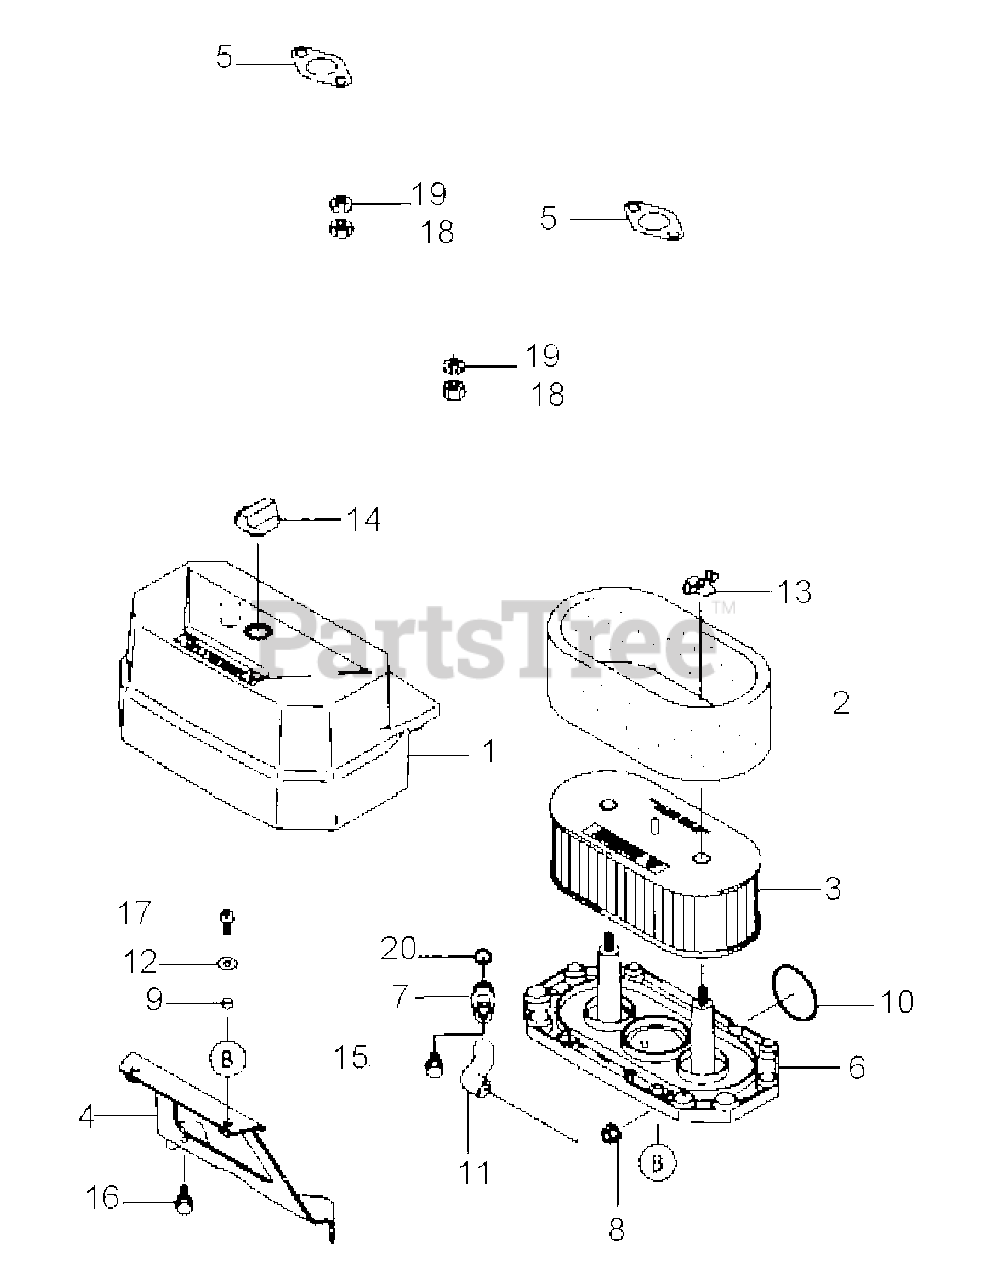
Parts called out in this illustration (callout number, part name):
1	AIR FILTER CASE
2	PRE FILTER ELEMENT
3	AIR FILTER ELEMENT
5	MUFFLER GASKET
9	SPACER, 6.2x7.9x5
15	FLANGED BOLT
16	FLANGED BOLT
19	SPRING WASHER
20	O-RING 10mm
